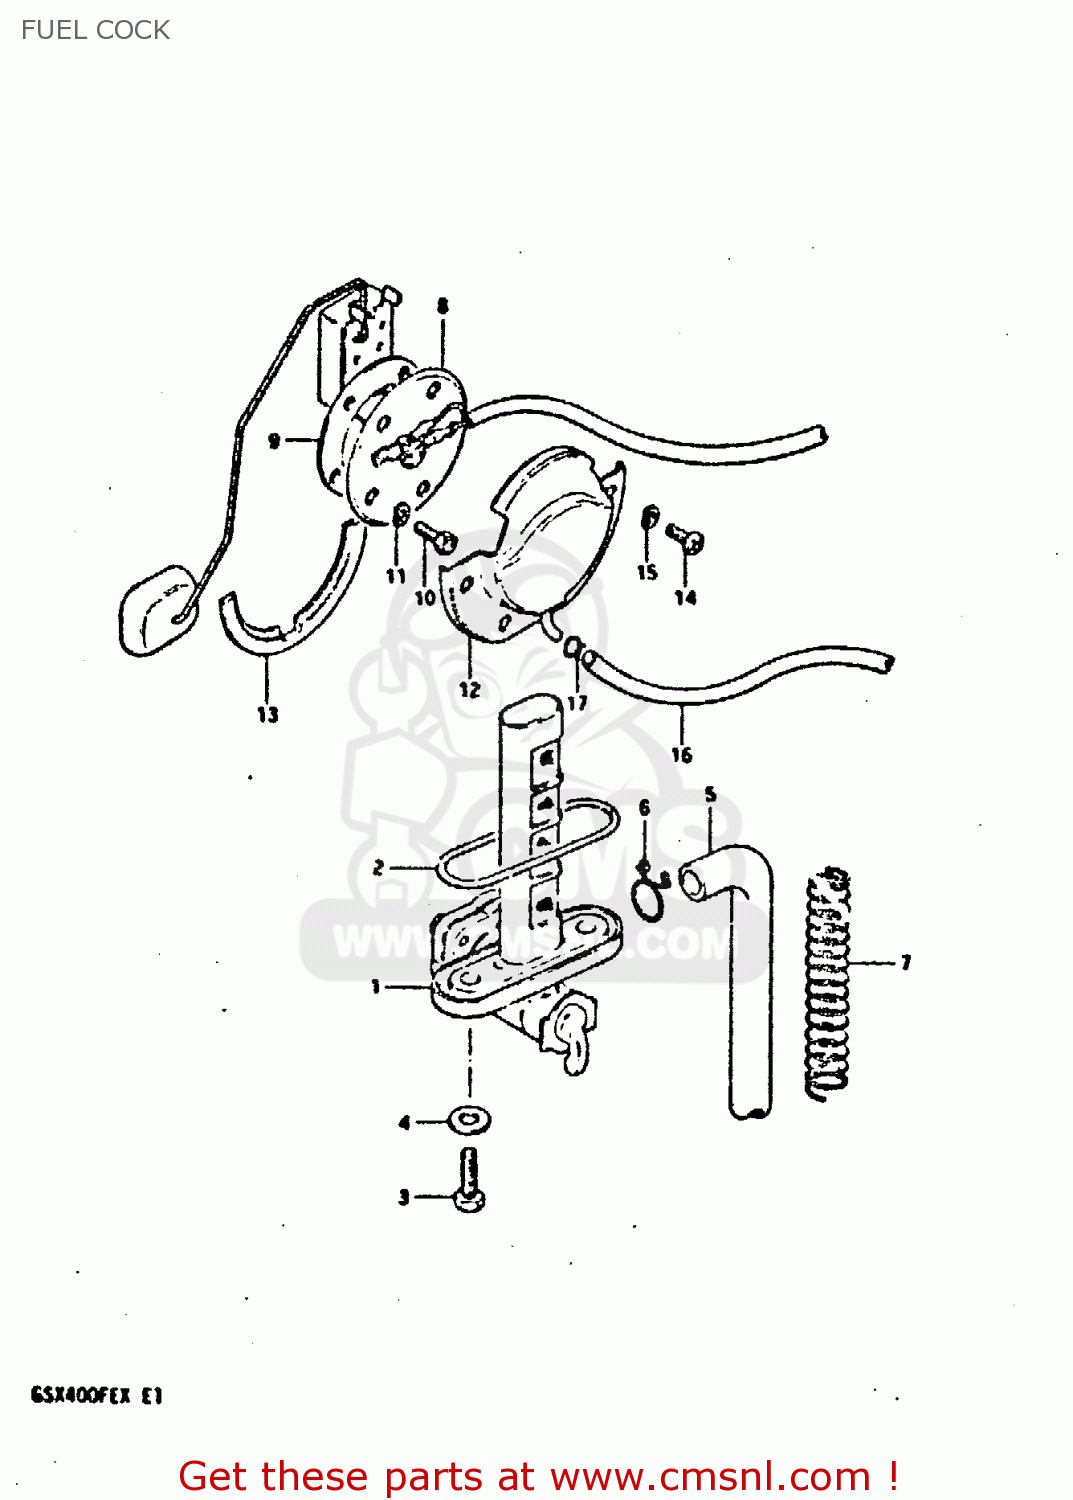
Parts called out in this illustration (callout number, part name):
1	COCK ASSEMBLY,FUEL
2	O RING
3	SCREW(6X14)
4	GASKET
5	HOSE
6	CLIP
7	SPRING
8	GAUGE, FUEL LEVER
9	GASKET,FUEL LEVEL GAUGE (NAS)
10	SCREW
11	LOCK WASHER
12	PLATE,FUEL DRAIN
13	GASKET,FUEL DRAIN PLATE (NAS)
14	SCREW
15	LOCK WASHER
16	HOSE,FUEL
17	CLIP
